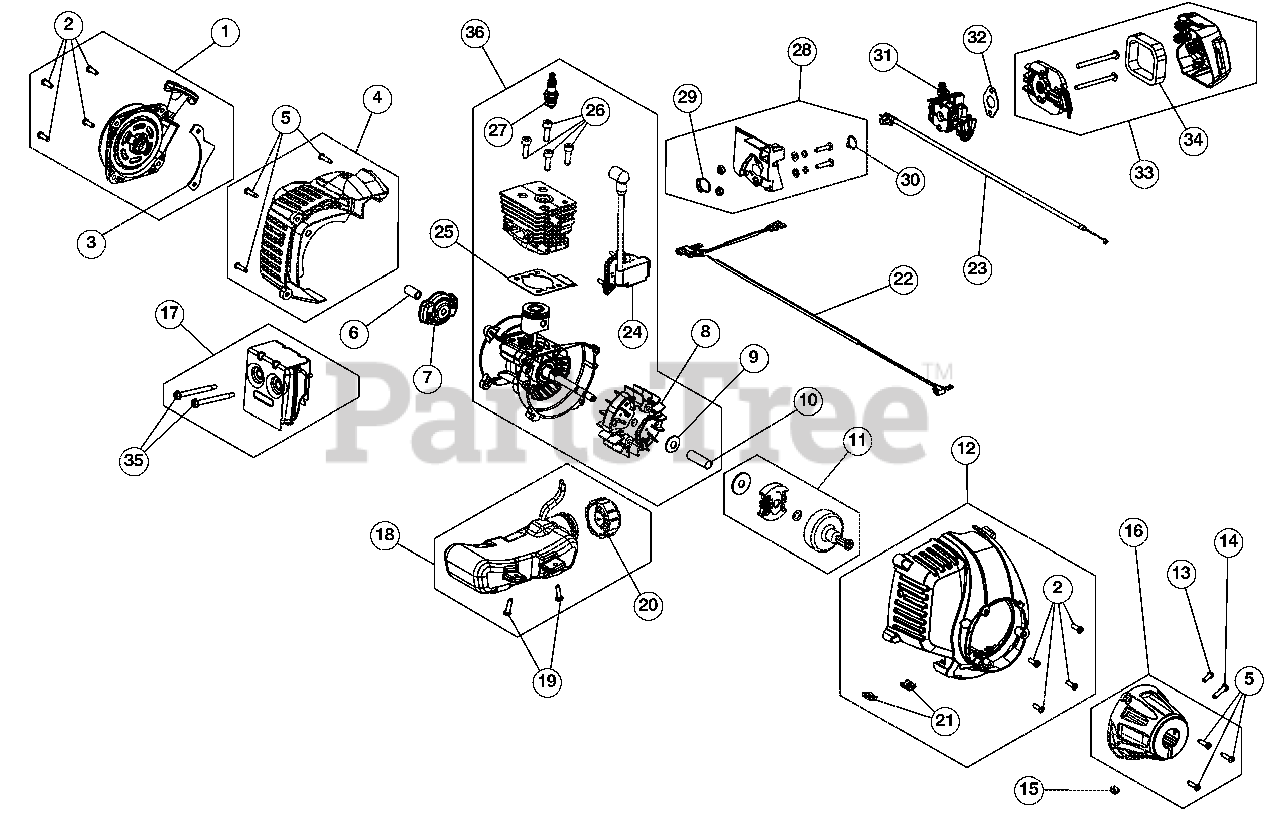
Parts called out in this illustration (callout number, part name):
1	Rear Cover Assembly (Incl. 2 & 3)
2	Starter Screw
3	Starter Assembly Guard (Incl. 2)
4	Rear Engine Cover Assembly (Incl. 5)
5	Cover Screw
6	Adapter
7	Pawl Assembly
8	Flywheel Assembly
9	Washer
10	Spacer
11	Clutch Assembly
12	Front Engine Cover Assembly (Incl. 2 & 21)
13	Anti-Rotation Screw
14	Clamp Screw
15	Clamp Nut
16	Clutch Cover Assembly (Incl. 5)
17	Muffler Assembly (Incl. 35)
18	Fuel Tank Assembly (Incl. 19 & 20)
19	Tank Screw
20	Fuel Cap
21	U-Shaped Nut
22	Lead Wires
23	Throttle Cable
24	Module Assembly
25	Cylinder Gasket
26	Cylinder Bolt
27	Spark Plug
28	Insulator Assembly (Incl. 29 & 30)
29	Insulator O-Ring
30	Carburetor O-Ring
31	Carburetor
32	Carburetor Gasket
33	Air Cleaner Assembly (Incl. 34)
34	Air Cleaner Filter
35	Muffler Screws
36	Short Block Assembly
